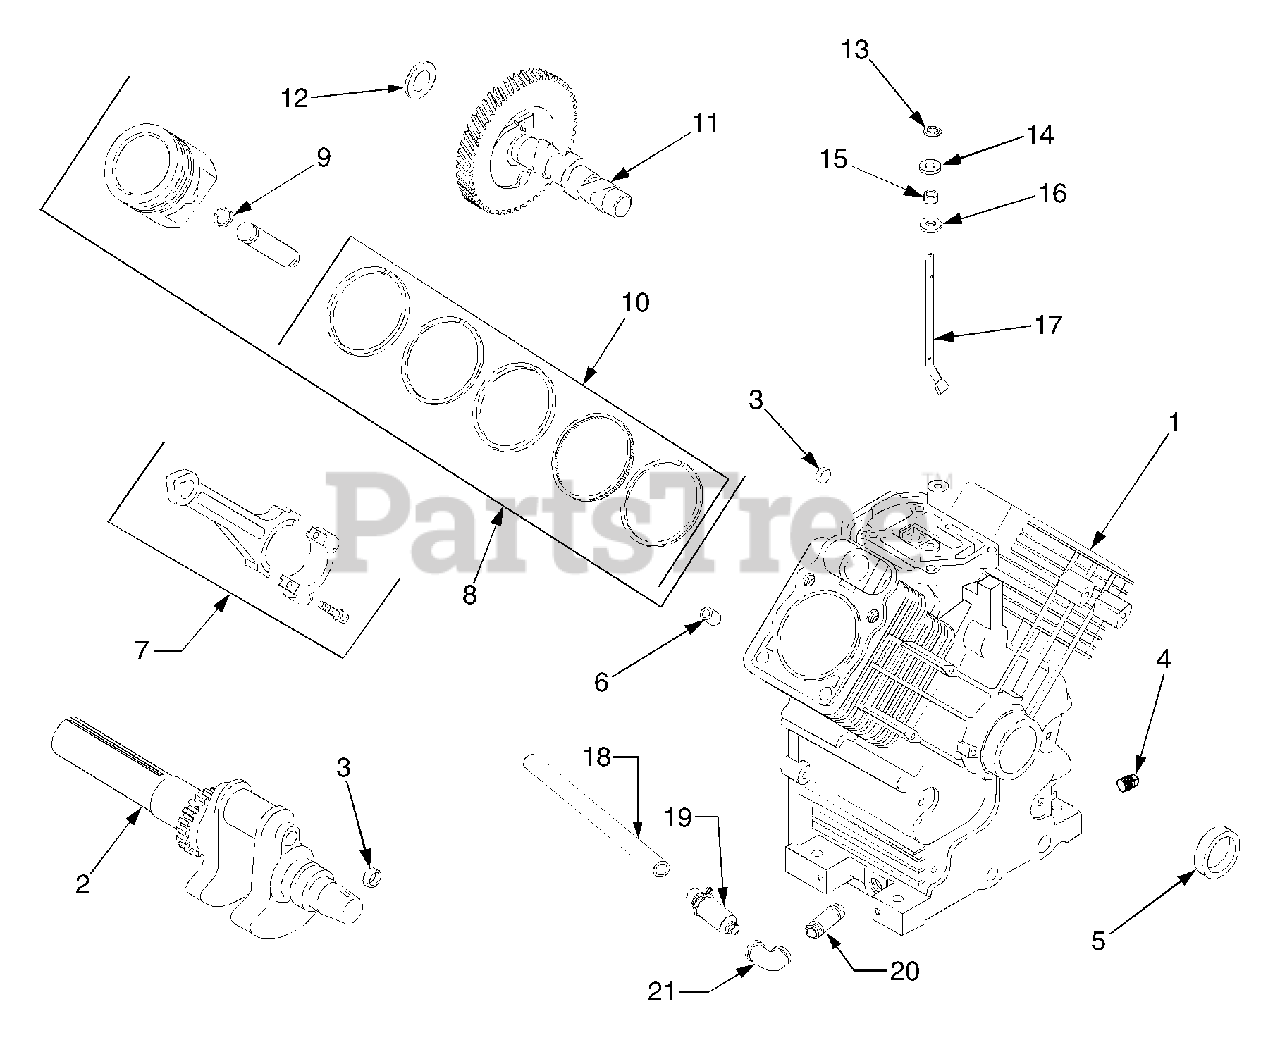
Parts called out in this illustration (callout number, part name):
1	Engine, Complete
2	Crankshaft
3	Plug, Cup
4	Plug, Hex Head, 3/8 NPTF
5	Seal, Oil
6	Pin, Locating
7	Rod, Connecting, Std
8	Piston w/Ring Set, Std
9	Retainer, Piston Pin
10	Ring Set, Std & .003
11	Camshaft
12	Shim, Camshaft, .0320
13	Ring, Retainer
14	Washer, Nylon
15	Seal, Governor Cross Shaft
16	Washer, Plain
17	Shaft, Governor Cross
18	Hose, Oil Drain
19	Drain, Oil
20	Pipe, Straight
21	Elbow, 90°.
